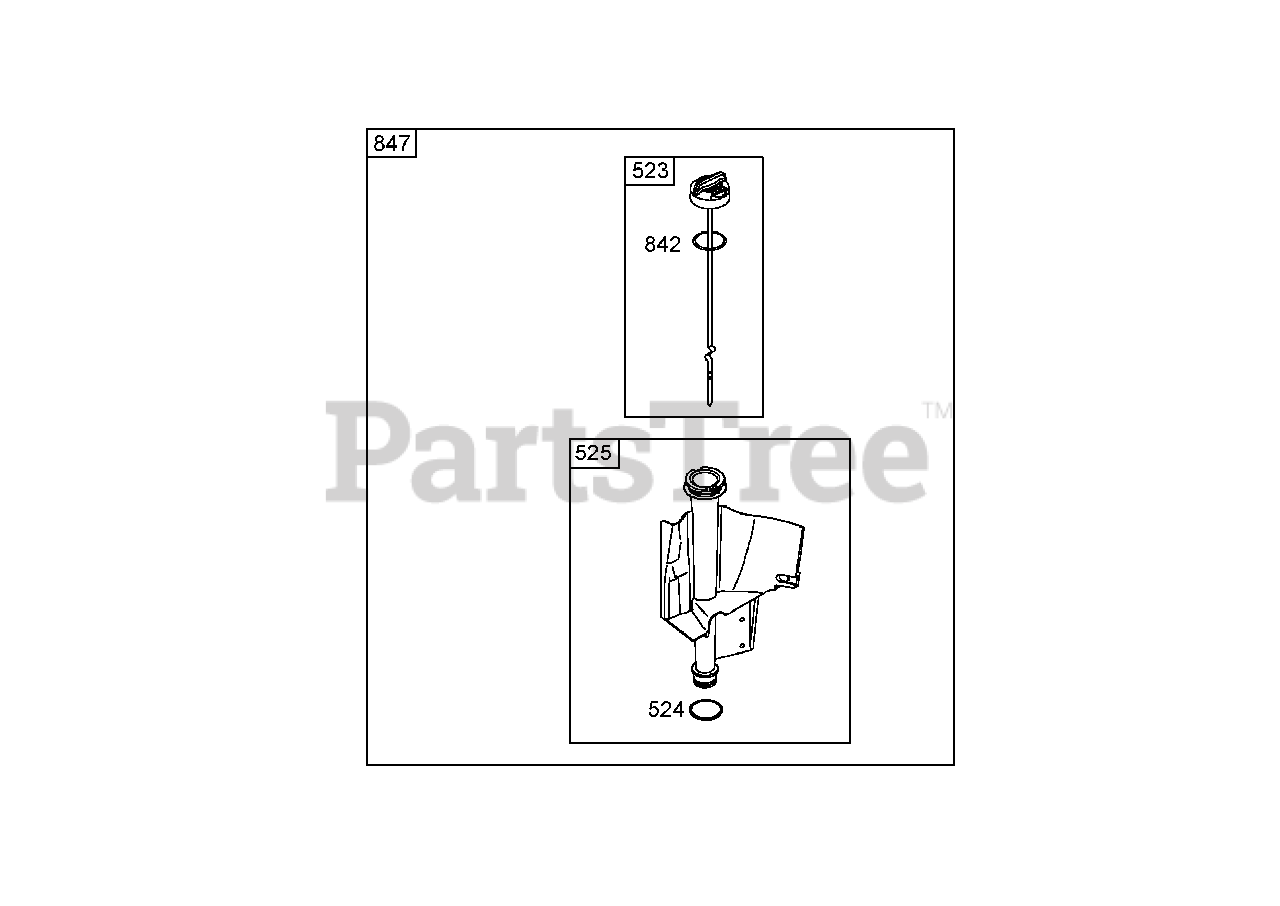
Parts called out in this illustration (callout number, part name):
523	Dipstick
524	Seal-O Ring
525	Tube-Dipstick
842	Seal-O Ring
847	Dipstick and Tube ASM
